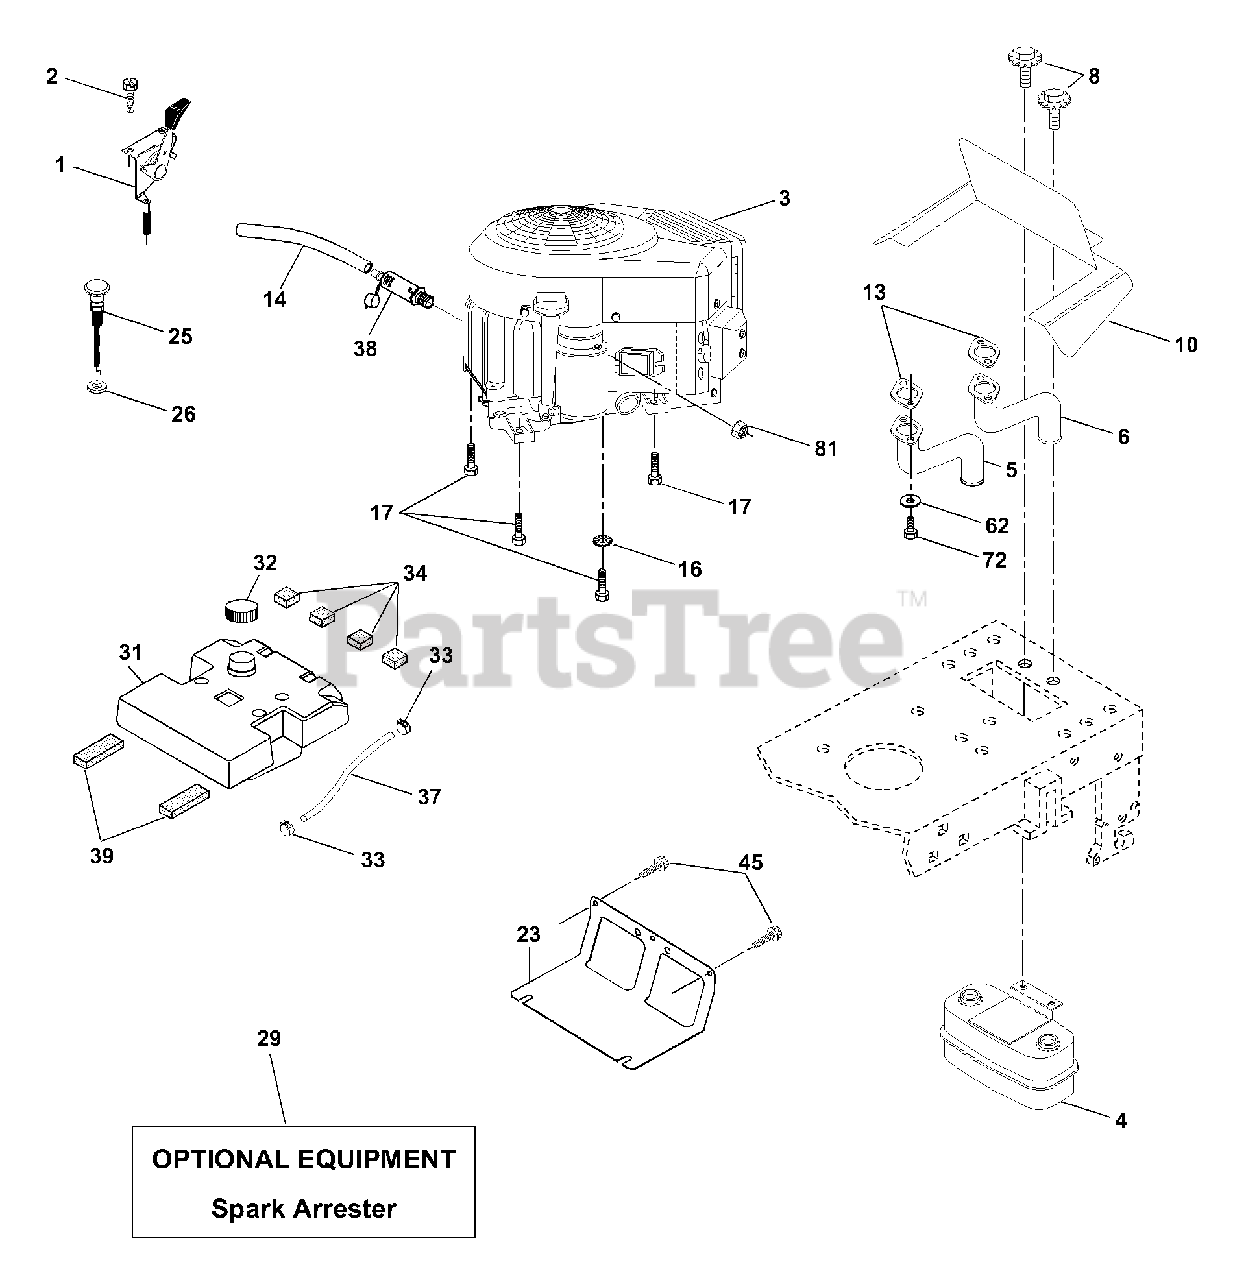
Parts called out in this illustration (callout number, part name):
1	Control Th/ch Flag
2	Screw Hex Thd Cut 1/4-20x5/8 T
3	Engine Kawa
5	Exhaust Tube LH
6	Exhaust Tube RH
8	Bolt 5/16-18 x 3/4
10	Shield Heat Muffler
13	Gasket
14	Tube Drain Oil Easy
16	Washer Lock Ext Tooth 3/8
23	Shield BRN/DBR Guard
25	Control Choke
26	Nut Keps 3/8-24
29	Kit Spark Arrestor (Flat Scrn)
32	Cap Asm Fuel W/sym Vented
33	Clamp Hose Black
34	Pad Spacer 1 x 1 x 1
37	Line Fuel
38	Plug Drain Oil Easy
39	Pad Idler 1.75 x .75 x .06
40	Bushing Snap Nyl Black Fuel Line
45	Screw Hex Wsh Thdrol 3/8-16 x 3/4
72	Screw Hex Hd Cap 5/16-18 x 3/4
78	Screw 3/8-16 x 1-1/4
81	Nut Flange M-8-1.25
105	Screw 3/8-16 x 1
